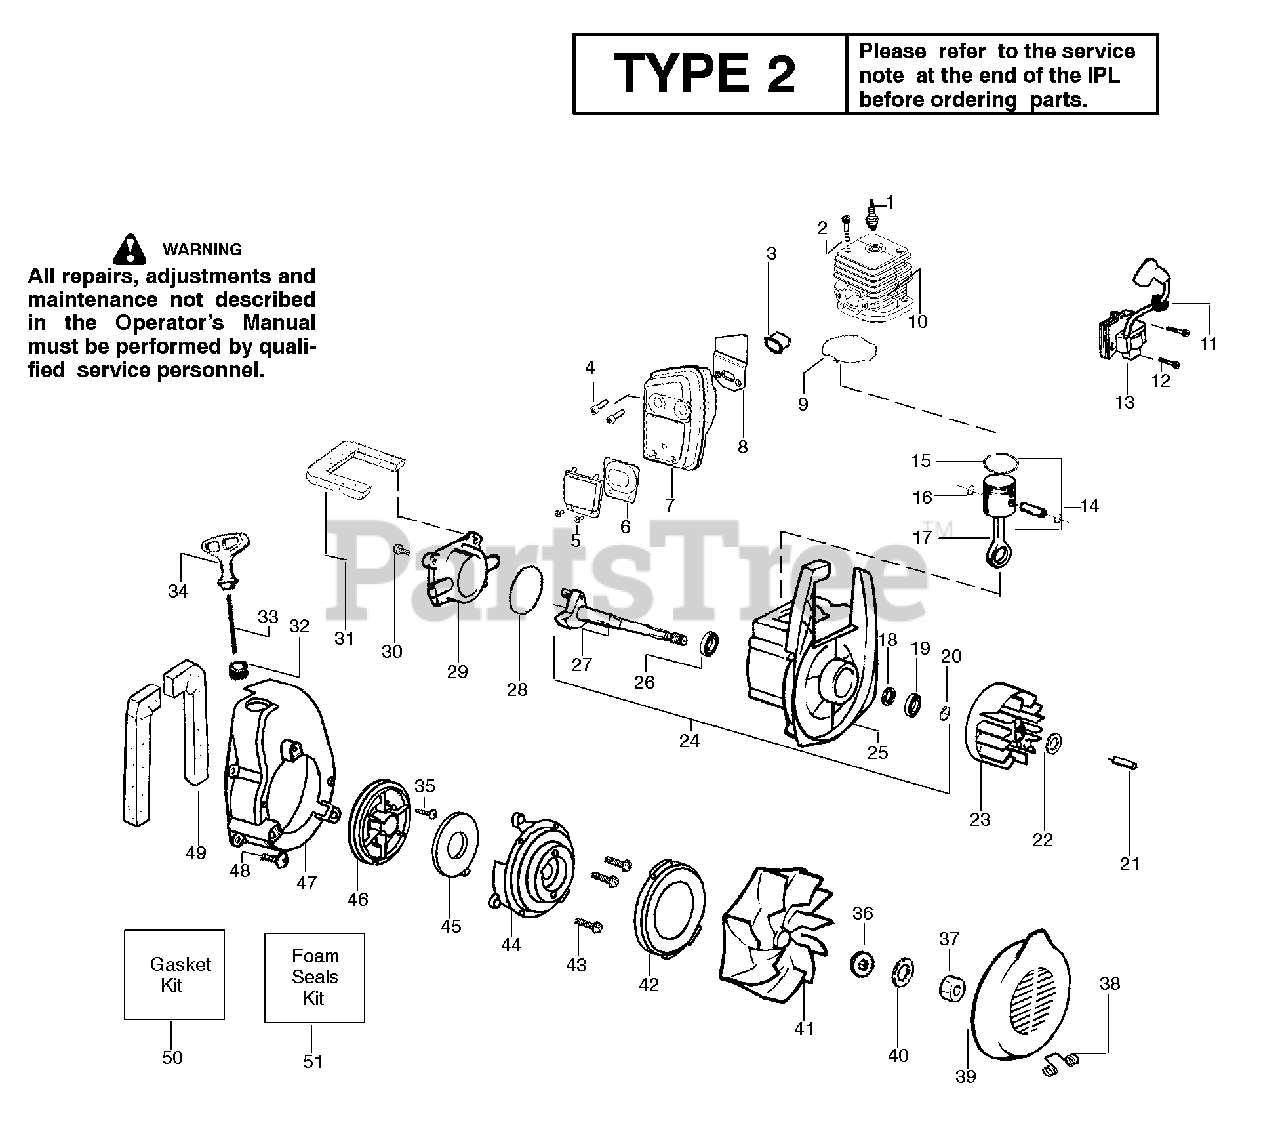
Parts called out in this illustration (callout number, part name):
1	Spark Plug (RCJ-6Y)
3	Insulator-Heat
4	Screw-Muffler-Internal
6	Kit-Spark Screen
7	Kit-Muffler
8	Gasket-Baffle (kit)
9	Gasket-Cylinder (kit)
10	Kit-Cylinder
11	Grommet-Ign. Module
12	Screw-Ignition Module
13	Ignition Module
14	Kit-Piston
15	Piston Ring
16	Retainer-Piston Pin
17	Assy-Connecting Rod
18	Kit-Crankcase Seal
19	Bearing-Outer
20	Retainer Ring-C'chaft
21	Spacer-Flywheel
23	Assy-Flywheel
24	Assy-Crankcase/Crankshaft
25	Assy-Crankcase
26	Bearing-Inner
27	Assy-Crankshaft
28	O-ring-C/case (kit)
29	Cover-Crankcase
30	Screw
31	Foam-219mm (kit)
32	Eyelet-Flange
33	Kit-Rope
34	Handle-Starter
35	Screw-Rope
36	Washer-Belleville
38	Spring-Return Cover
39	Inlet Door
40	Washer-Flat
41	Assy-Impeller
42	Seal-Ring
44	Housing-Pulley
45	Spring-Starter
46	Kit-Starter Pulley
47	Fan Housing
48	Screw
49	Foam-182mm (kit)
50	Kit-Gasket
51	Kit-Foam Seals
